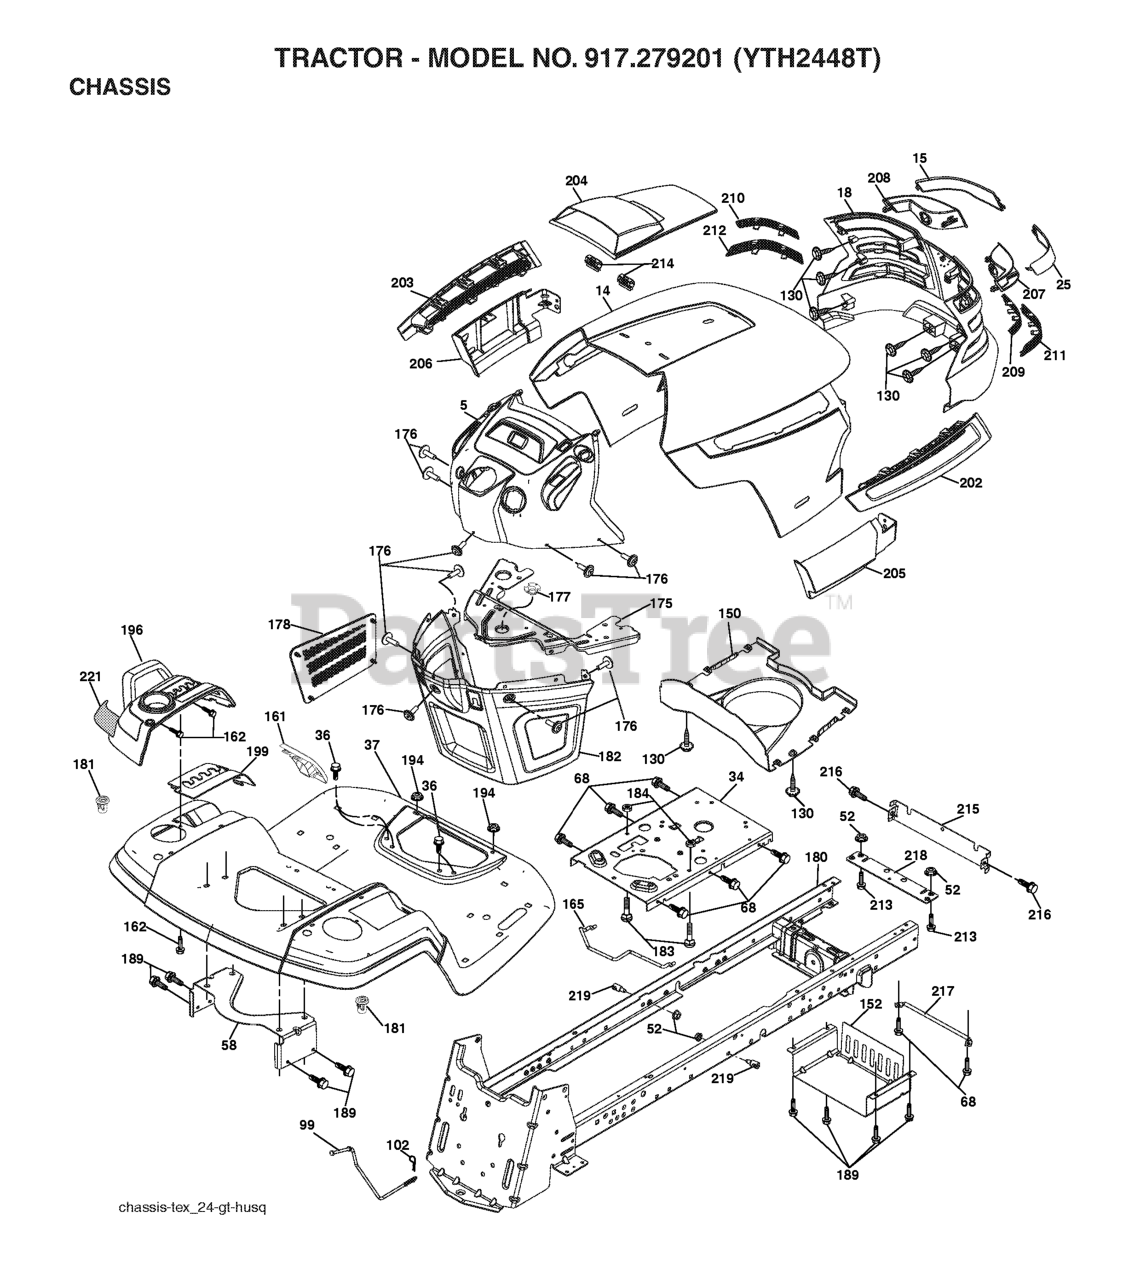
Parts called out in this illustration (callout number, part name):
5	DASH.HUSQ.UPR.ELE.SVMD
14	HOOD.PNT.HUSQVARNA.GT.
15	LENS.LH.TEX.GT.HUSQ.CL
18	GRILLE.ASM.TEX.GT.HUSQ
25	LENS.RH.TEX.GT.HUSQ.CL
34	PLATE.ENGINE.WELDED.CHASSIS
37	FENDER.PNT.TX.GT.CH/FW.ORANGE
52	LOCKNUT
58	BRKT.SUPPORT.FNDR/TANK
68	Screw 5/16-18 x 1/2 Hex, Self Tapping 5/16-18 x 1/2
99	ROD.BYPASS.K46.TG
102	RETAINER M
130	SCREW
139	BOLT, SHOULDER 5/16-18
150	AIR.DUCT.TEXGT.HUSQ.SV
152	SHIELD.BROWNING.WTEXLT
156	SCREW
161	CONSOLE.FUEL.WINDOW.HU
162	SCREW.HI-LO.CONSOLE
165	SUPPORT.TANK.REAR.W/TEX
175	PLATE.CROSSMEMBER.HUSQ
176	SCREW.#10-24X5/8.RN.QU
177	BUSHING, STEERING
178	CARGO.ASM.NET.TXGT.W/C
180	CHASSIS.WLDMT.TX.GT.05
181	BUSHING.MNT.FEND.CRGO.
182	DASH.LOWER.COMMON.12V.
184	SPACER.FENDER
185	BOLT.CARRIAGE.5/16-18
189	SCREW
194	NUT LOCK HEX FLANGE 5/16-18
196	RP CONSOLE.ASM.DECKLFT.W/
199	PLATE.DECK.LIFT.HUSQVARNA.GT
202	VENT.SIDE.HOOD.HUSQ.RH.GREY
203	VENT.SIDE.HOOD.HUSQ.LH.GRAY
204	VENT.TOP.HOOD.HUSQVARN
205	SKIRT.HOOD.SIDE.HUSQ.RH.GREY
206	SKIRT.HOOD.SIDE.HUSQ.LH.GREY
207	BEZEL.RH.TEX.GT.HUSQ
208	BEZEL.LH.TEX.GT.HUSQ
209	INSERT.HEX.GRILL.HUSQ.GREY
210	INSERT.HEX.GRILL.HUSQ.
211	INSERT.HEX.GRILL.HUSQ.
212	INSERT.HEX.GRILL.HUSQ.
213	BOLT
214	CLIP.RETAINER.TINNER.
215	COVER.CHASSIS.FRONT.WE
216	SCREW, 5/16-18 X 1/2
217	ROD PIVOT CHASSIS/HOOD
218	X-PIECE.HOOD.STOP.NON/
219	STUD.FASTNER.W/ANTI-ROTATE
221	REFLECTOR.LH.TEX GT HU
